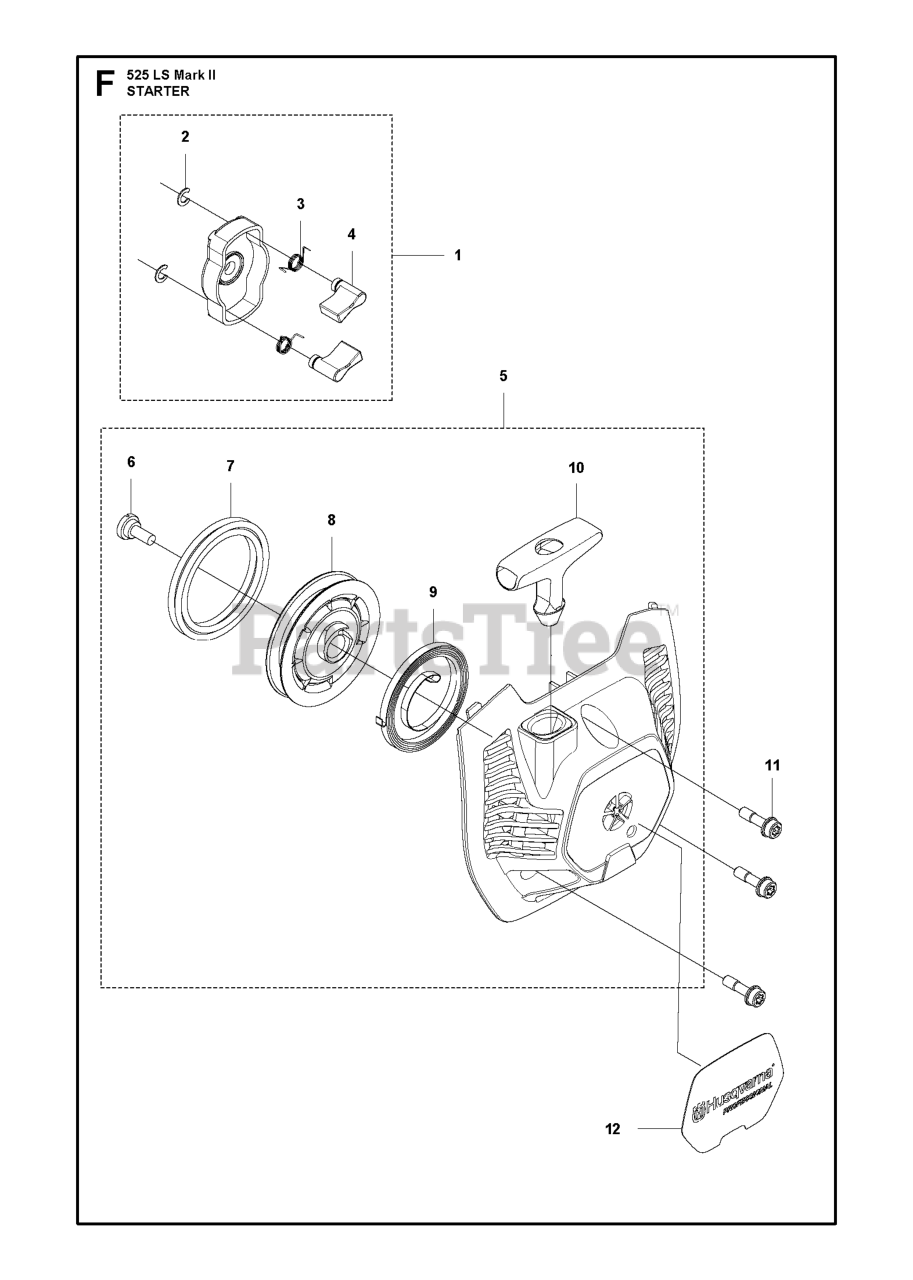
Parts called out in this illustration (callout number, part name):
5	STARTER ASSY
6	SCREW
8	STARTER PULLEY
10	STARTER HANDLE
11	BOLT
12	STARTER DECAL
